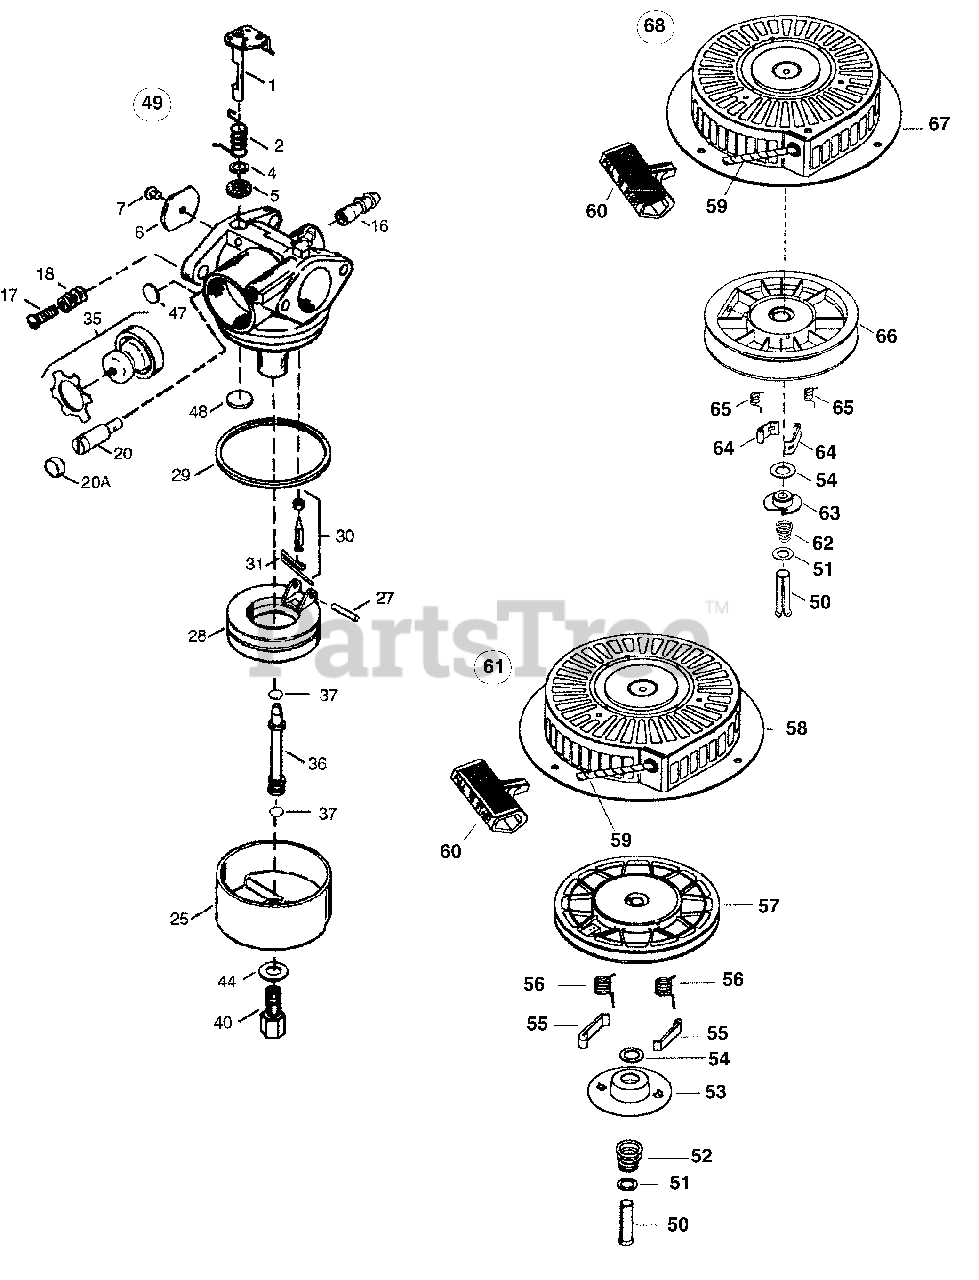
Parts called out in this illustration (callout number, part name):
1	Throttle Shaft & Lever Ass'y
2	Throttle Return Spring
4	Dust Seal Washer
5	Dust Seal (Throttle)
6	Throttle Shutter
7	Shutter Screw
16	Fuel Fitting
17	Throttle Crack/Idle Speed Screw
18	Tension Spring
20	Idle Restrictor Screw
20A	Idle Restrictor Screw Cap
25	Float Bowl
27	Float Shaft
28	Float
29	Float Bowl"O" Ring
30	Inlet Needle, Seat & Clip
31	Spring Clip
35	Primer Bulb/Retainer Ring
36	Main Nozzle Tube
37	Main Nozzle Tube"O" Ring
40	High Speed Bowl Nut
44	Bowl Nut Washer
47	Welch Plug, Idle Mixture Well
48	Welch Plug, Atmospheric Vent
49	Carburetor Assembly
50	Spring Pin
52	Brake Spring
55	Starter Dog
56	Dog Spring
57	Pulley & Rewind Spring Ass'y
58	Starter Housing Ass'y
59	Starter Rope (98")
60	Starter Handle
61	Rewind Starter Ass'y
62	Brake Spring
64	Starter Dog
65	Dog Spring
66	Pulley & Rewind Spring Ass'y
67	Starter Housing Ass'y
68	Rewind Starter Ass'y
